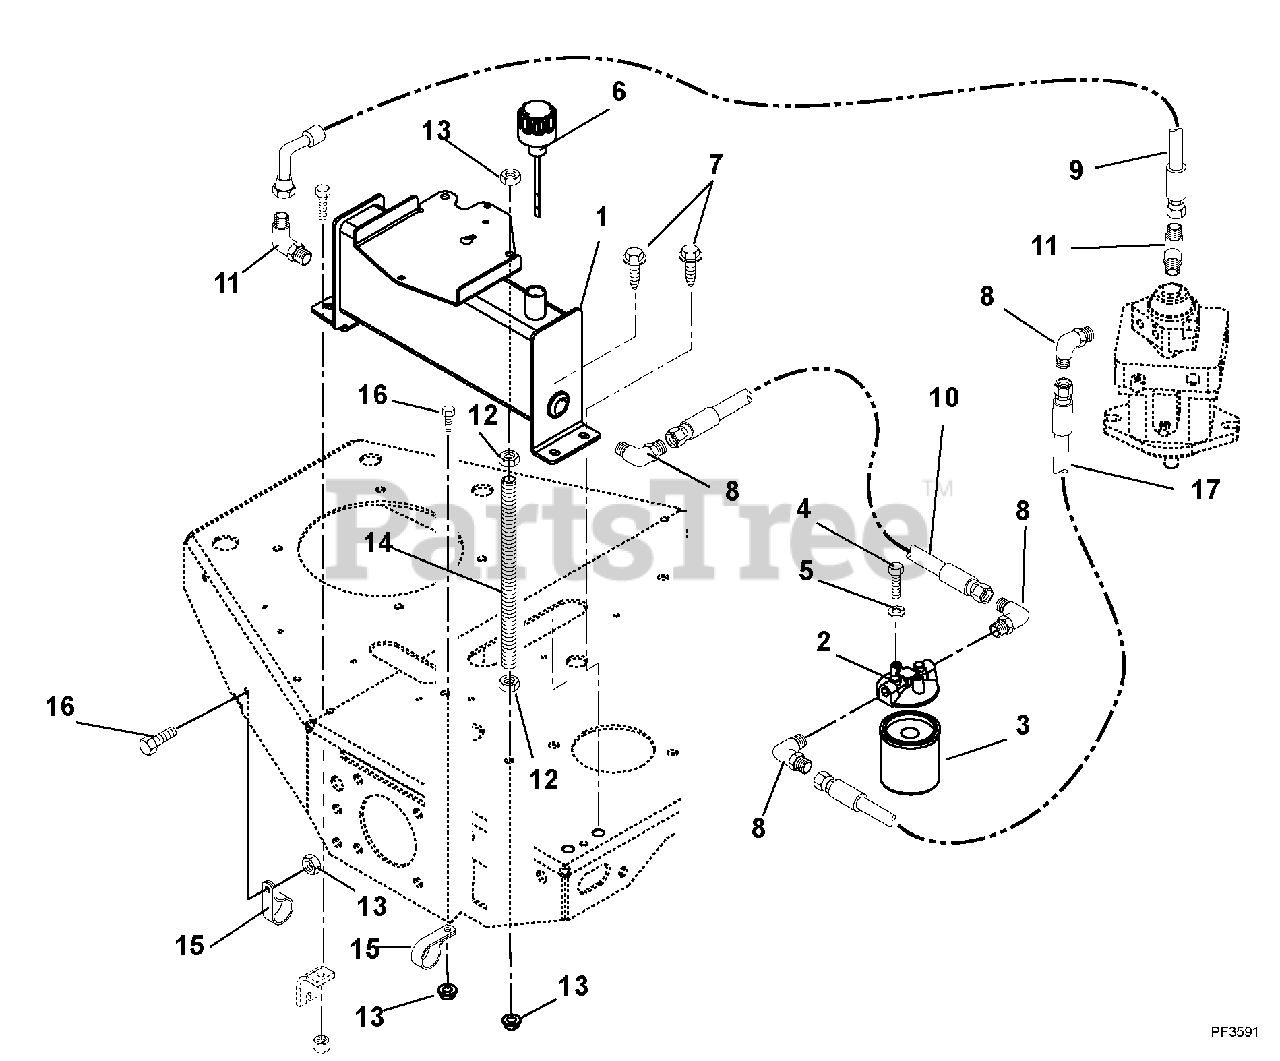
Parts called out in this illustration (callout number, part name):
1	Weldment, Hydraulic Tank
2	Head, Filter
3	Filter, Oil
4	Bolt-Hex .25-20 x .50 Grade 5
5	Washer-Locking .25 x .062 Regular
6	Dipstick, Hydraulic Tank, Push In
7	Screw-Tapping .38-16 x .75 Hex Washer Head
8	Fitting, Hydraulic
9	Hose, Hydraulic
10	Hose, Hydraulic
11	Fitting, Hydraulic Elbow
12	Nut-Hex .38-16
13	Nut-Locking-Top-Flange .38-16
14	Rod, Extension
16	Bolt-Hex .38-16 x 1.00 Grade 5
17	Hose, Hydraulic
